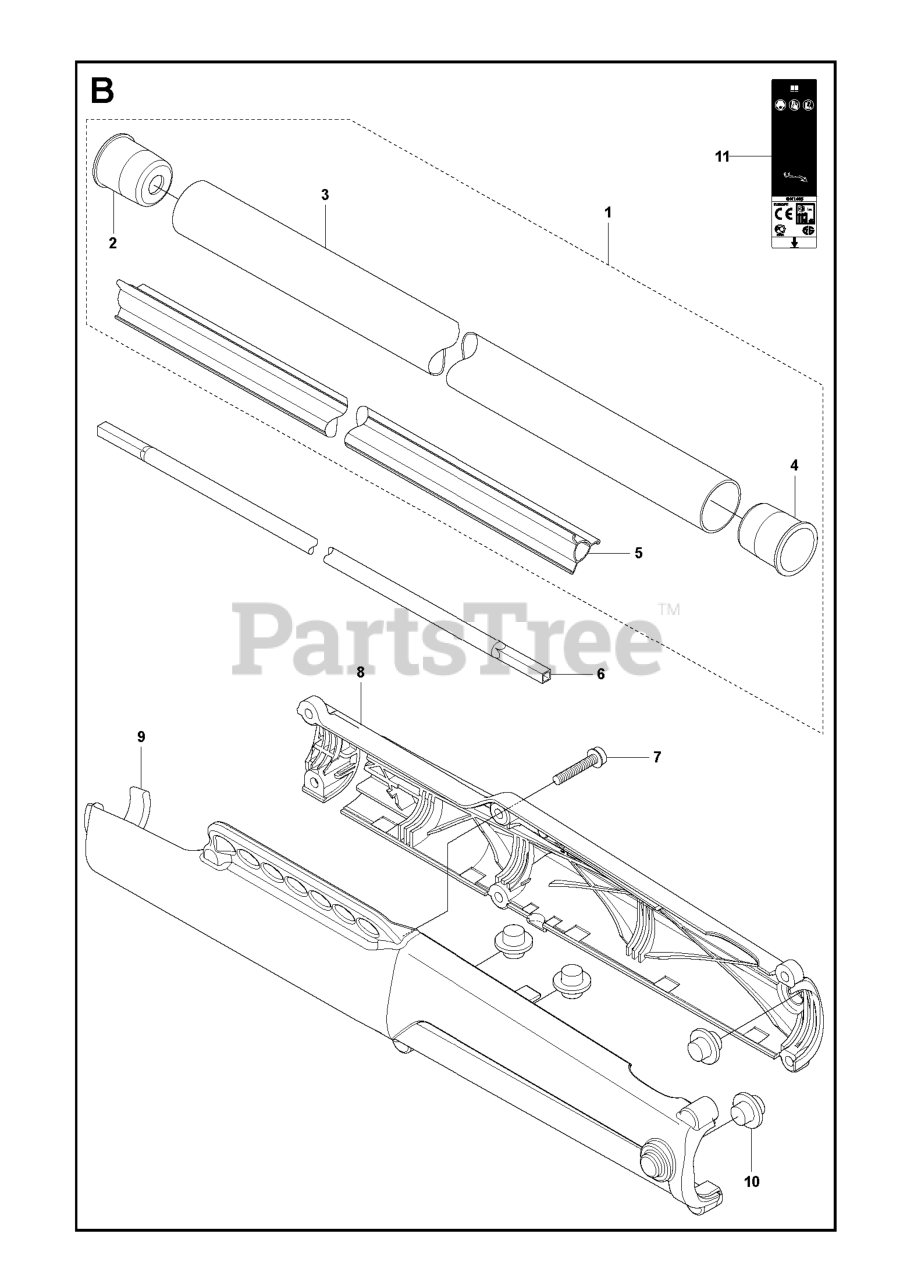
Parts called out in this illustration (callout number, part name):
1	TUBE
2	PLUG
3	TUBE
5	GUIDE
6	SHAFT
7	SCREW IHSCFT
10	VIBRATION ABSORBER
11	LABEL WARNING TRIMMERS AND BRU
